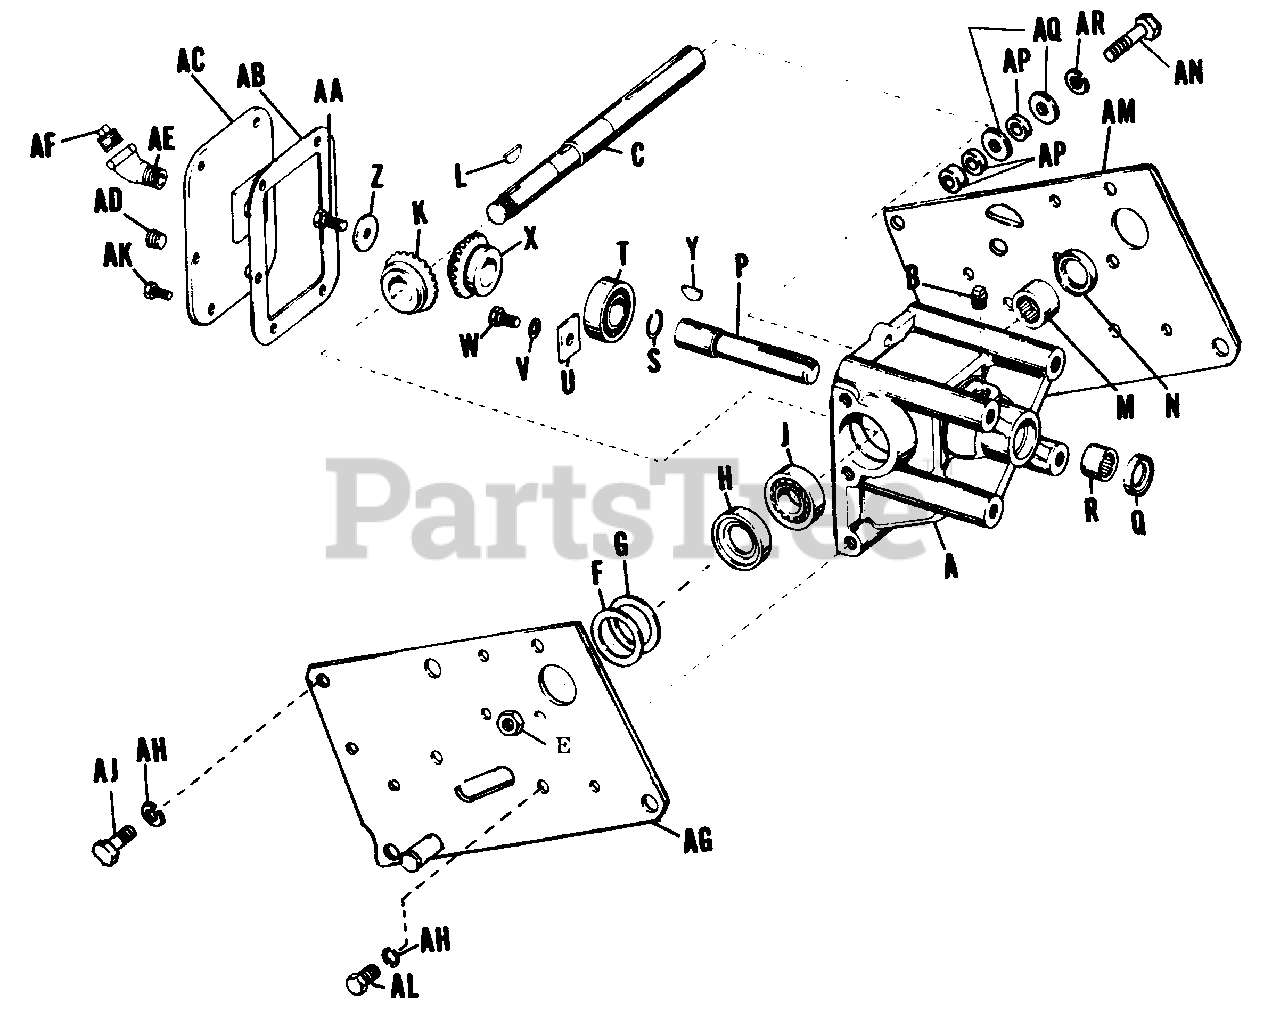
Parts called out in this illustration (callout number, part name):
A	Bevel Gear Housing, W/Bearings
B	Pipe Plug
C	Drive Shaft
E	Hex Jam Nut
F	Shim (As Required)
J	Ball Bearing
K	Bevel Driven Gear
M	Needle Bearing
P	Driven Shaft
R	Needle Bearing
S	Retaining Ring
T	Ball Bearing
U	Bearing Clamp Plate
V	Lock Washer, 5/16"
W	Hex Capscrew, 5/16"-18 x 5/8" lg.
X	Bevel Driven Gear
AA	Hex Capscrew, 5/16"-18 x 3/4" lg.
AC	Housing Cover Assembly
AD	Pipe Plug
AE	Street Elbow
AF	Pipe Plug
AG	R.H. Side Plate
AH	Lock Washer, 7/16"
AJ	Hex Capscrew, 7/16"-14 x 1" lg.
AK	Hex Capscrew, 1/4"-20 x 5/8" lg.
AL	Hex Capscrew, 7/16"-14 x 1-1/4" lg.
AM	L.H. Side Plate
AN	Hex Capscrew. 7/16"-14 x 2" lg.
AQ	Washer 7/16"
AR	Lock Washer 7/16"
